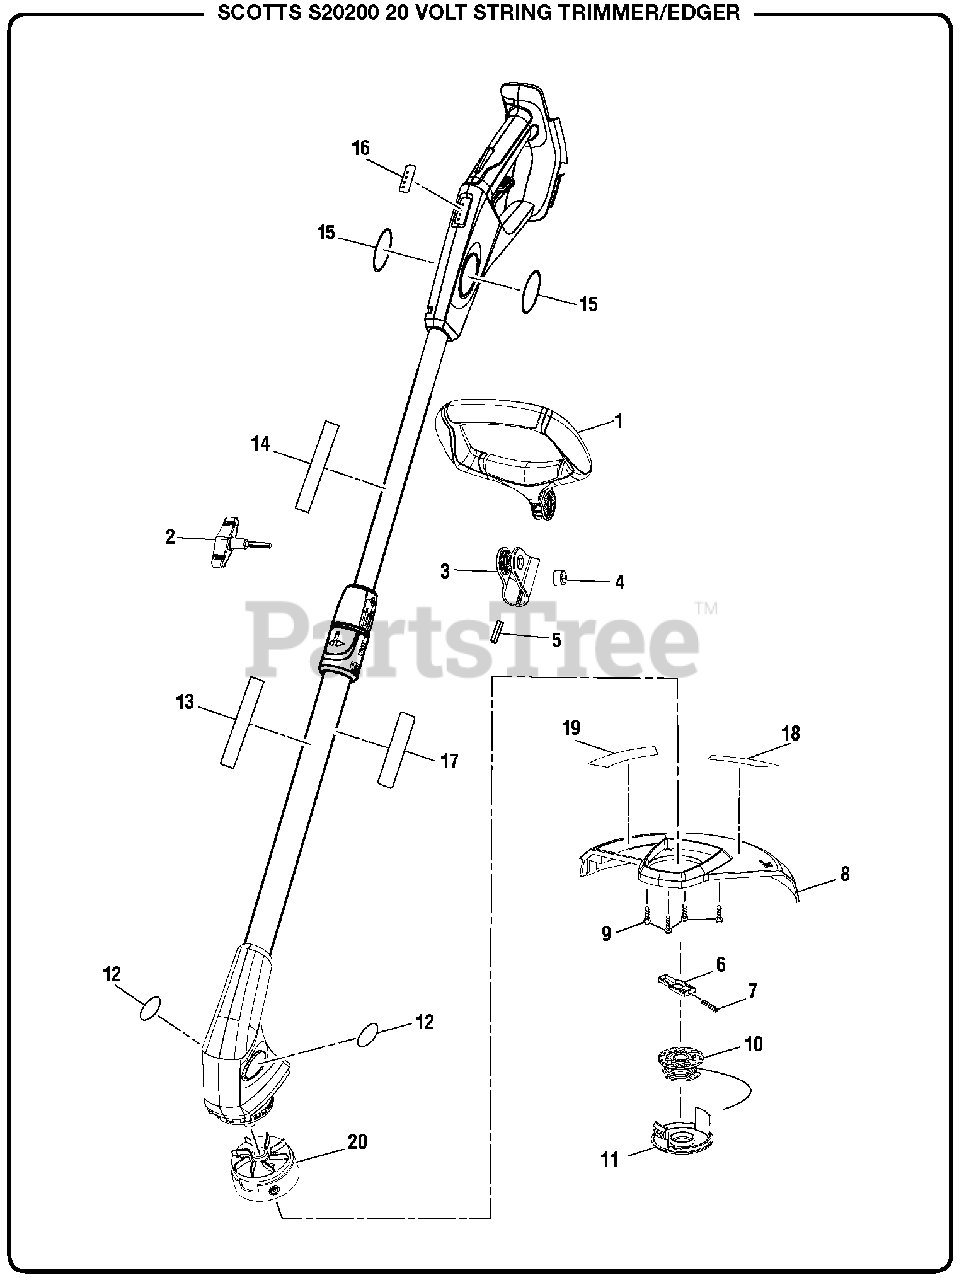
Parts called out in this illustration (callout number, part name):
1	Front Handle
3	Clamp
4	Hex Nut (M6)
5	Rubber Plate
6	Slider Assembly
8	Guard Assembly
9	Screw (M4 x 16 mm)
10	Spool Assembly
11	Spool Cover
12	Motor Housing Logo Label
13	Warning Icon Label
14	Data Label
15	Handle Logo Label
16	Fuel Gauge Label
17	Warning Label (French/Spanish)
18	No Bump Label
19	Cutting Length Label
20	Spool Base w/Slider Assembly
